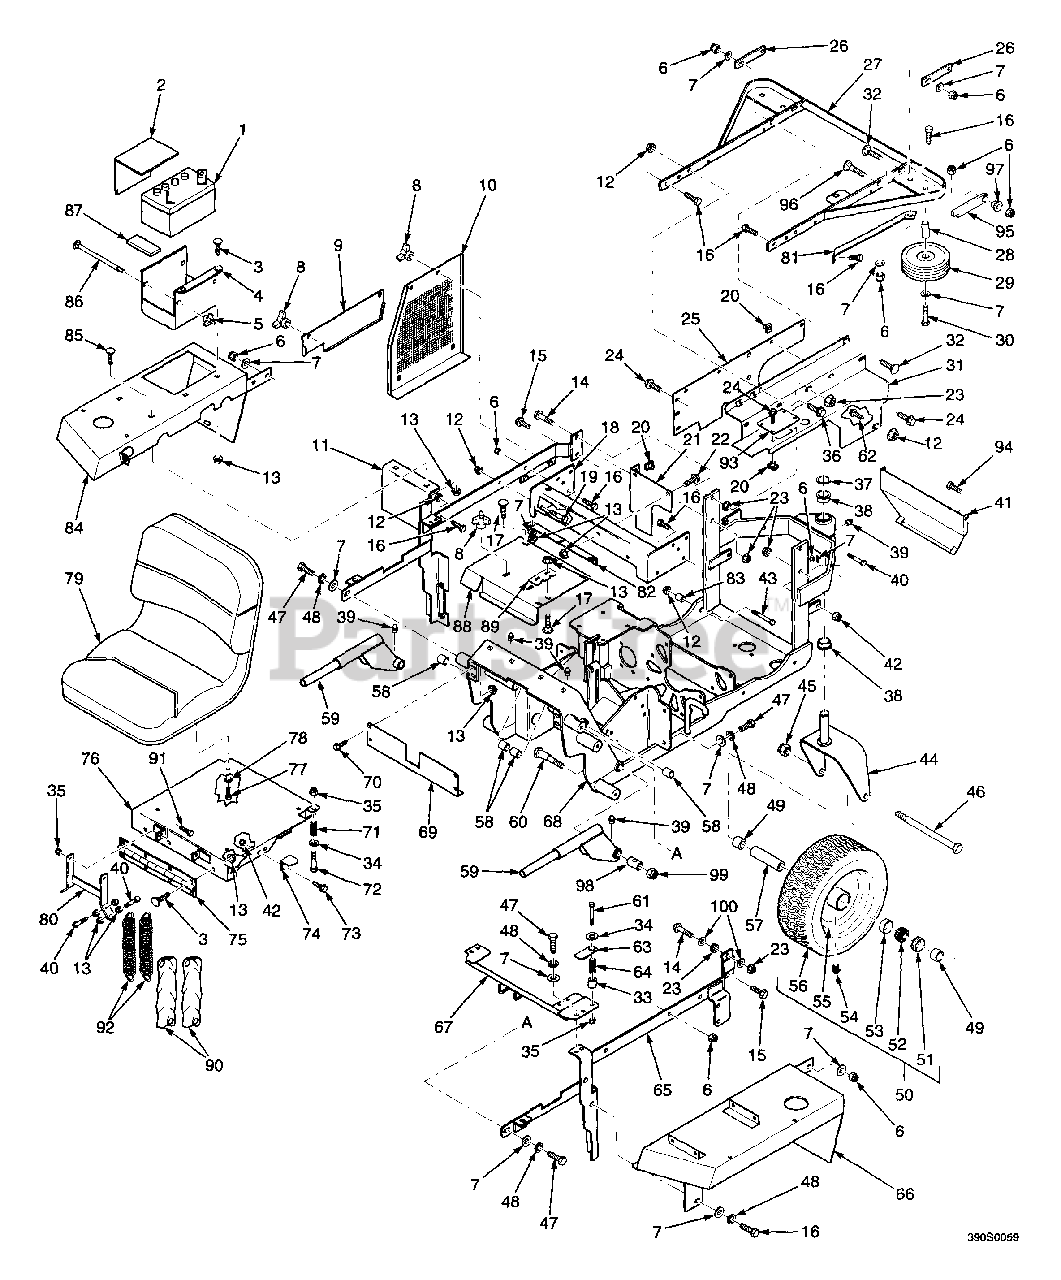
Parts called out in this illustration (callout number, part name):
1	Battery
2	Cover, Battery
3	Carriage Bolt, 5/16-18 x 3/4
4	Box, Battery
5	Wingnut, Plastic, 1/4-20
6	Hex Locknut, Elastic Stop, 3/8-16
7	Flatwasher, 3/8 (.391 x .938 x .105)
8	Wingnut, Plastic, 3/8-16"
9	Belt Cover, Front
10	Belt Cover, Rear
11	Frame, Right Side
12	Serr. Fl. Hex Nut, 3/8-16"
13	Serr. Fl. Hex Nut, 5/16-18"
14	Serr. Fl. Hex Head CPSCR, 1/2-13 x 2.00"
15	Serr. Fl. Hex Head CPSCR, 1/2-13 x 1-1/4"
16	Bolt, Hex Head, 3/8-16 x 1-1/4"
17	Carriage Bolt, 5/16-18 x 1/2"
18	Cross Brace, Frame
19	Bolt, Hex Head, 3/8-16 x 1-1/2"
21	Heat Shield, Front
22	Serr. Fl. Hex Head CPSCR, 5/16-18 x 1-1/4"
23	Serr. Fl. Hex Nut, 1/2-13
24	Serr. Fl. Hex Head CPSCR, 1/4-20 x 3/4"
25	Heat Shield, Side
27	Frame, Bagger Support
28	Spacer, Wheel
29	Wheel, Bumper
30	Bolt, Hex Head, 3/8-16 x 2-1/2"
31	Heat Shield, Top
32	Carriage Bolt, 3/8-16 x 1-1/4"
33	Pivot, Seat Latch
34	Flatwasher, 5/16 (.375 x .875 x .083)
35	Hex Locknut, Elastic Stop, 5/16-18
36	Serr. Fl. Hex Head CPSCR, 3/8-16 x 3/4"
37	Retaining Ring, 1-1/4"
38	Bushing, Oilite, 1.127 ID
39	Grease Fitting
40	Bolt, Hex Head, 5/16-18 x 1-3/4"
41	Shield, Engine
42	Hex Lock Nut, Elastic Stop, 1/4-20
43	Bolt, Hex Head, 3/8-16 x 3.00"
44	Yoke, Rear Caster
45	Hex Locknut, Elastic Stop, 5/8-11
46	Bolt, Hex Head, 5/8-11 x 9.00"
47	Bolt, Hex Head, 3/8-16 x 1.00"
48	Lockwasher, 3/8"
49	Spacer
50	Tire and Wheel Assembly
51	Seal
52	Cone, Bearing
53	Cup, Bearing
54	Grease Fitting
55	Rim
56	Tire
57	Sleeve, Rear Tire
58	Bushing, Oilite, .753 ID
59	Shaft, Push Arm Mounting
60	Pivot, Pusharm
61	Bolt, Hex Head, 5/16-18 x 2-3/4"
62	Serr. Fl. Hex Head CPSCR, 3/8-16 x 3/4"
63	Latch, Seat
64	Spring
65	Frame, Left Side
66	Fender, Left With Decal
67	Crossbrace
68	Frame, Main
69	Crossmember, Front
70	Serr. Fl. Hex Head CPSCR, 5/16-18 x 3/4"
71	Spring, Seat
72	Bolt, Special
73	Serr. Fl. Hex Head CPSCR, 1/4-20 x 3/4"
74	Actuator, Seat Switch
75	Hinge, Seat
76	Seat Base
77	Bolt, Hex Head, 5/16-18 x 3/4"
78	Lockwasher, 5/16"
80	Mounting Brkt Wlmt, Deck Springs
81	Brace, Bucket Support
82	Hinge, Gearbox Cover
83	Spacer
84	Fender, Right With Decal
85	Carriage Bolt, 5/16-18 x 3/4"
86	Carriage Bolt, 1/4-20 x 6.00"
87	Pad, Rubber
88	Cover, Gearbox With Decal
89	Bracket, Dump Valve
90	Spring Cover
91	Bolt, 5/16-18 x 1.00"
92	Spring, Deck
93	Cover, Access Hole
94	Bolt, Hex Head 1/4-20 x 3/4"
95	Prop Rod, Hopper
96	Carr. Bolt, 3/8-16 x 1-1/2"
97	Washer, Step
98	Bushing, 1.003 ID x 2.10"
99	Nut, 3/4-16 UNF Elastic Stop
100	Flatwasher, 1/2 (.562 x 1.375 x .109)
